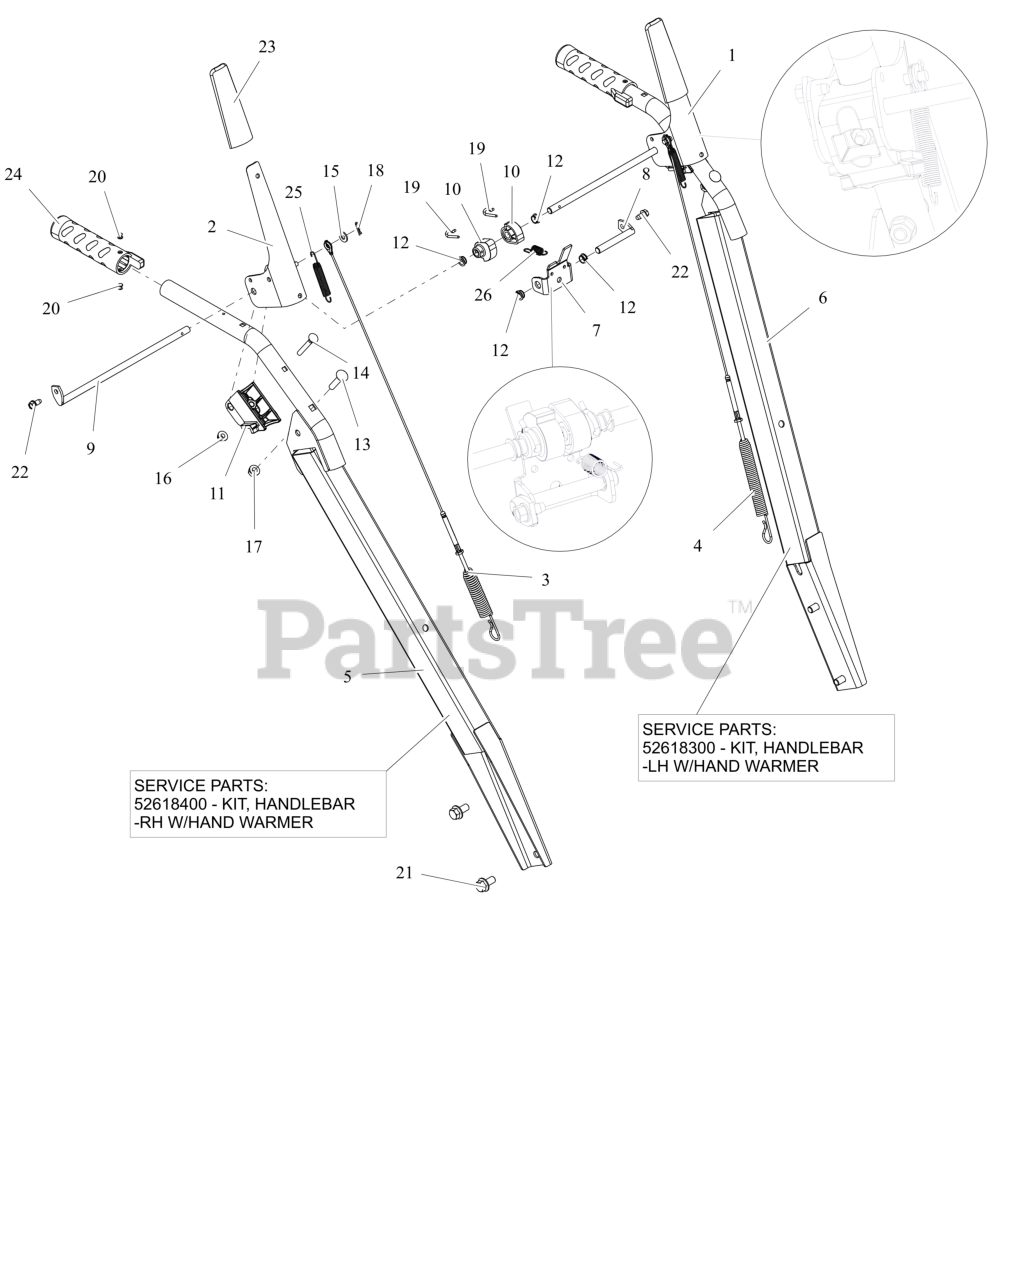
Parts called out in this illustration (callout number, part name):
1	LEVER, CLUTCH-LH
2	LEVER, CLUTCH-RH
3	CABLE, AUGER (DELUXE & PRO)
4	CABLE, UPPER TRACTION
5	HANDLEBAR- ROBUST - RH LINEAR
5	KIT, HB-RH W/WARM GRIP LINEAR
6	HANDLEBAR- ROBUST - LH LINEAR
6	KIT, HB-LH W/WARM GRIP LINEAR
7	BRACKET, INTERLOCK ARM
8	ROD, PIVOT - INTERLOCK
9	ROD, PADDLE MOUNT - PRO
10	CAM, INTERLOCK
11	BLOCK, CLUTCH PADDLE
12	BUSHING, POLYLINER-.38 SNAPIN
13	BLT,RHSN .31-18X1.50 G5 ZCC
14	BLT-RDHDXLSQNK .25-20X2.0 G5YZ
15	WSHR,FLT .281X.625X.065 ZCC
16	NUT-LK-CTR-FLG .25-20 ZC120
17	NUT-LK-TOP-FLG .312-18 GF ZCC
18	PIN, HAIR #178 .06X.77 ZCC
19	PIN, SPRING CLIP
20	RVT-POP #43 .125X.313 STL ZINC
22	SCR-TAP .25-20X.50 HWH ZCC
23	COVER, PADDLE
24	GRIP, HANDLE - HEATED
25	SPRING, EXTENSION
26	SPRING-EXT .047X.438X1.45
